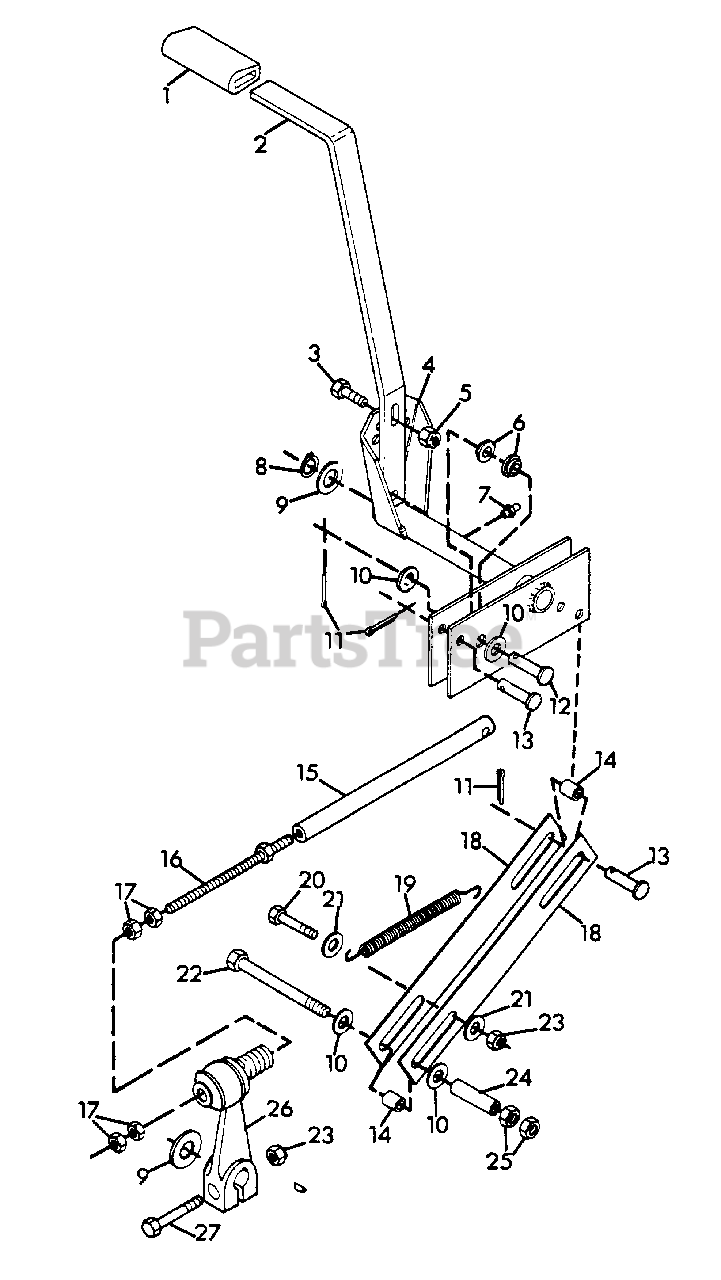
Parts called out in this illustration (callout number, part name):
1	GRIP, HANDLE
2	LEVER, FWD-REV
3	BOLT, HEX 3/8-16X1.00
4	WELDMENT, FWD-REV LEVER
5	NUT, LOCK 3/8-16
6	BUSHING, NYLON
7	FITTING, LUBE 1/4-28
8	RING, RETAINING .750 SHAFT
9	WASHER, FLAT .812X1.496X.134
10	WASHER, FLAT .406X.812X.065
11	PIN, COTTER .125X.750
12	PIN, CLEVIS .375X1.250
13	PIN, CLEVIS .375X1.31
14	SPACER
15	ROD, CONTROL FWD-REV
16	ROD, CONTROL EXTENSION
17	NUT, JAM 3/8-16
18	STRAP, NEUTRAL DETENT
19	SPRING, EXT. 5.5X.5X20 RATE
20	BOLT, HEX 5/16-18X1.25
21	WASHER, FLAT .344X.688X.065
22	BOLT, HEX 3/8-16X3.25
23	NUT, LOCK 5/16-18
24	SPACER
25	NUT, LOCK 3/8-16
26	ASSEMBLY, FWD-REV LEVER
27	BOLT, HEX 5/16-18X2.00
